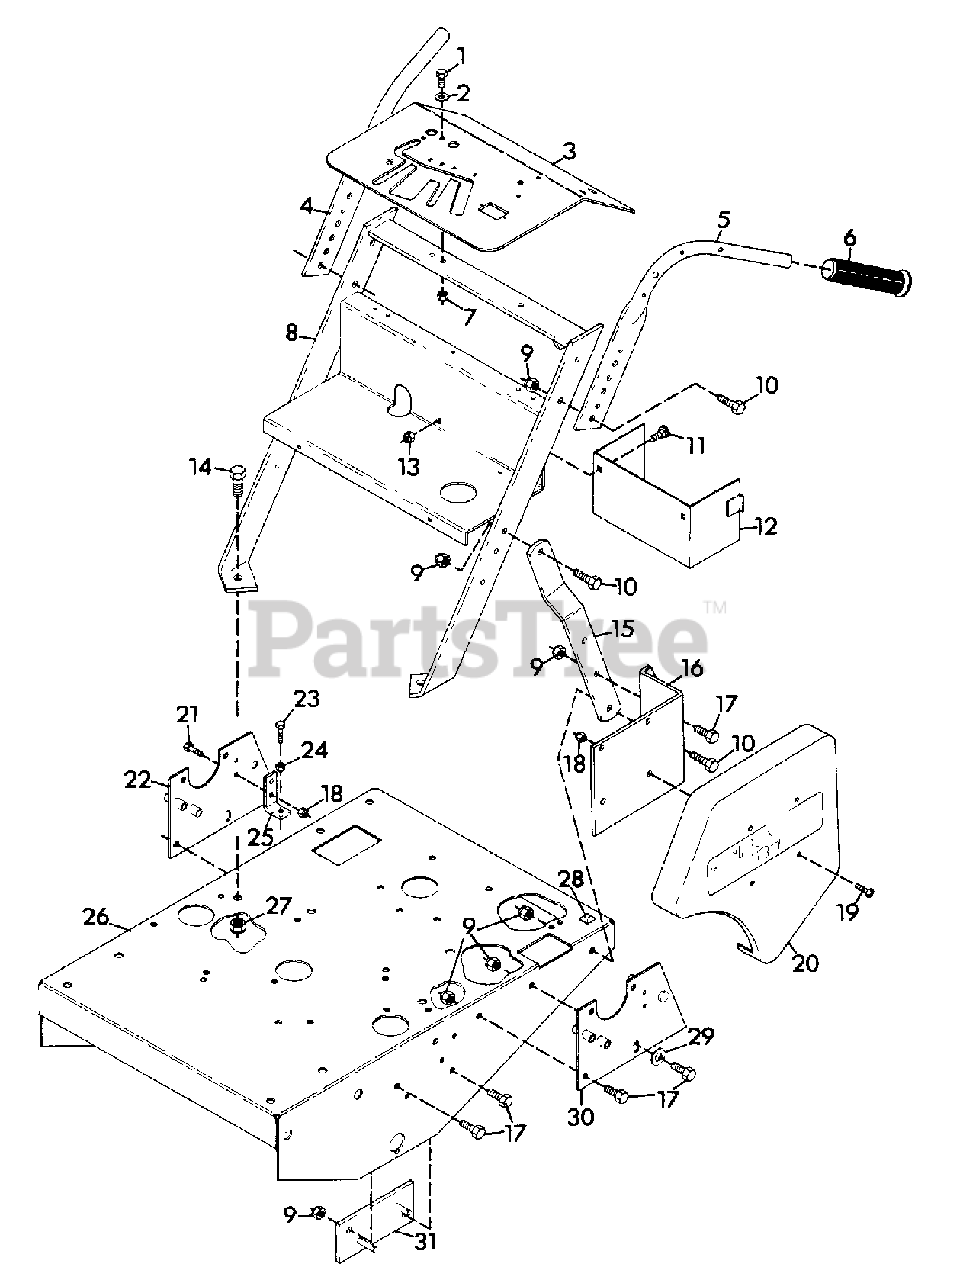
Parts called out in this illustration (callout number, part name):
1	BOLT, HEX 5/16-18X1.00
2	WASHER, FLAT .344X.688.X065
3	PLATE, SILK SCREEN
4	HANDLEBAR, R.H.
5	HANDLEBAR, L.H.
6	GRIP, HANDLEBAR
7	NUT, LOCK 5/16-18
8	WELDMENT, HANDLEBAR SUPPORT
9	NUT, LOCK 3/8-16
10	BOLT, HEX 3/8-16X1.25
11	BOLT, 5/16-18X.625 RD HD SQ NK
12	WELDMENT, BATTERY BOX
13	NUT, LOCK 5/16-18
14	BOLT, HEX 1/2-13X1.25
15	BRACE, HANDLEBAR SUPPORT
16	BRACKET, BELT GUARD L.H.
16	BRACKET, BELT GUARD R.H.
17	BOLT, HEX 3/8-16X1.00
18	NUT, LOCK 1/4-20
19	SCREW, MACHINE 1/4-20X.625 RD HD
20	GUARD, BELT L.H.
20	GUARD, BELT R.H.
21	BOLT, HEX 1/4-20X.625
22	WELDMENT, BEARING SUPPORT R.H.
23	BOLT, HEX 1/4-20X1.00
24	NUT, HEX 1/4-20
25	BRACKET
26	FRAME, PRO
27	NUT, LOCK 1/2-13
28	STOP
29	WASHER, FLAT .406X.812X.065
30	WELDMENT, BEARING SUPPORT L.H.
31	WELDMENT, BRAKE PIN PLATE L.H.
31	WELDMENT, BRAKE PIN PLATE R.H.
NS	DECAL, AMERICA
